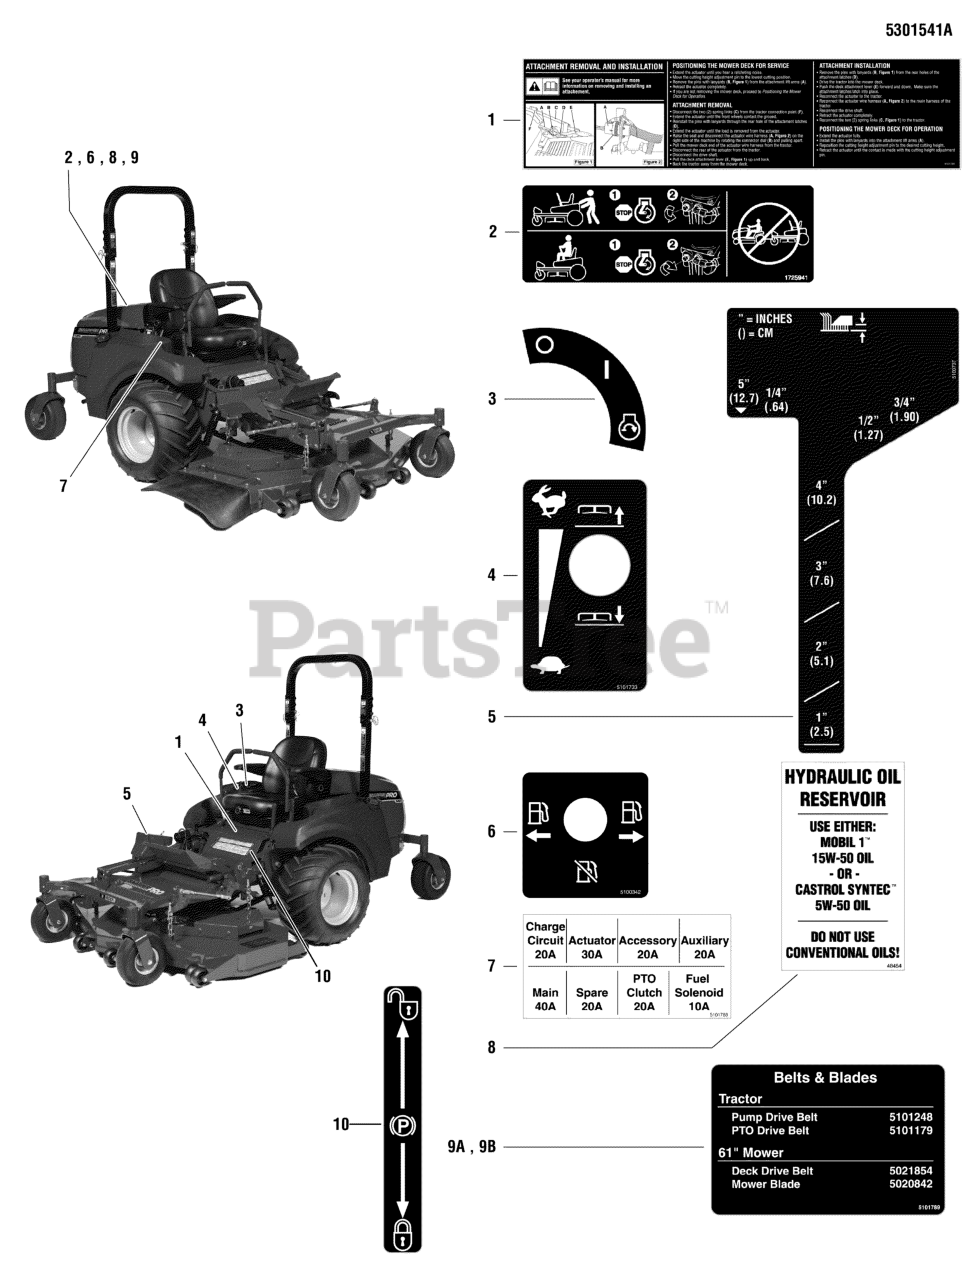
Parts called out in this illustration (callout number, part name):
1	DECAL, ATTACHMENT, S800X
2	DECAL, CZT HYRDO RELEASE
3	DECAL, IGNITION CONTROL
4	DECAL, CONTROL PANEL, S800X
5	DECAL, DECK HEIGHT, OUT FRONT MOWER
6	DECAL, FUEL VALVE
7	DECAL, FUSE LOCATION, S800X
8	DECAL, Oil Reservoir
9	DECAL, BELT & BLADE, S800X-72
9	DECAL, BELT AND BLADE, S800X
10	DECAL, PARKING BRAKE SYMBOLS
